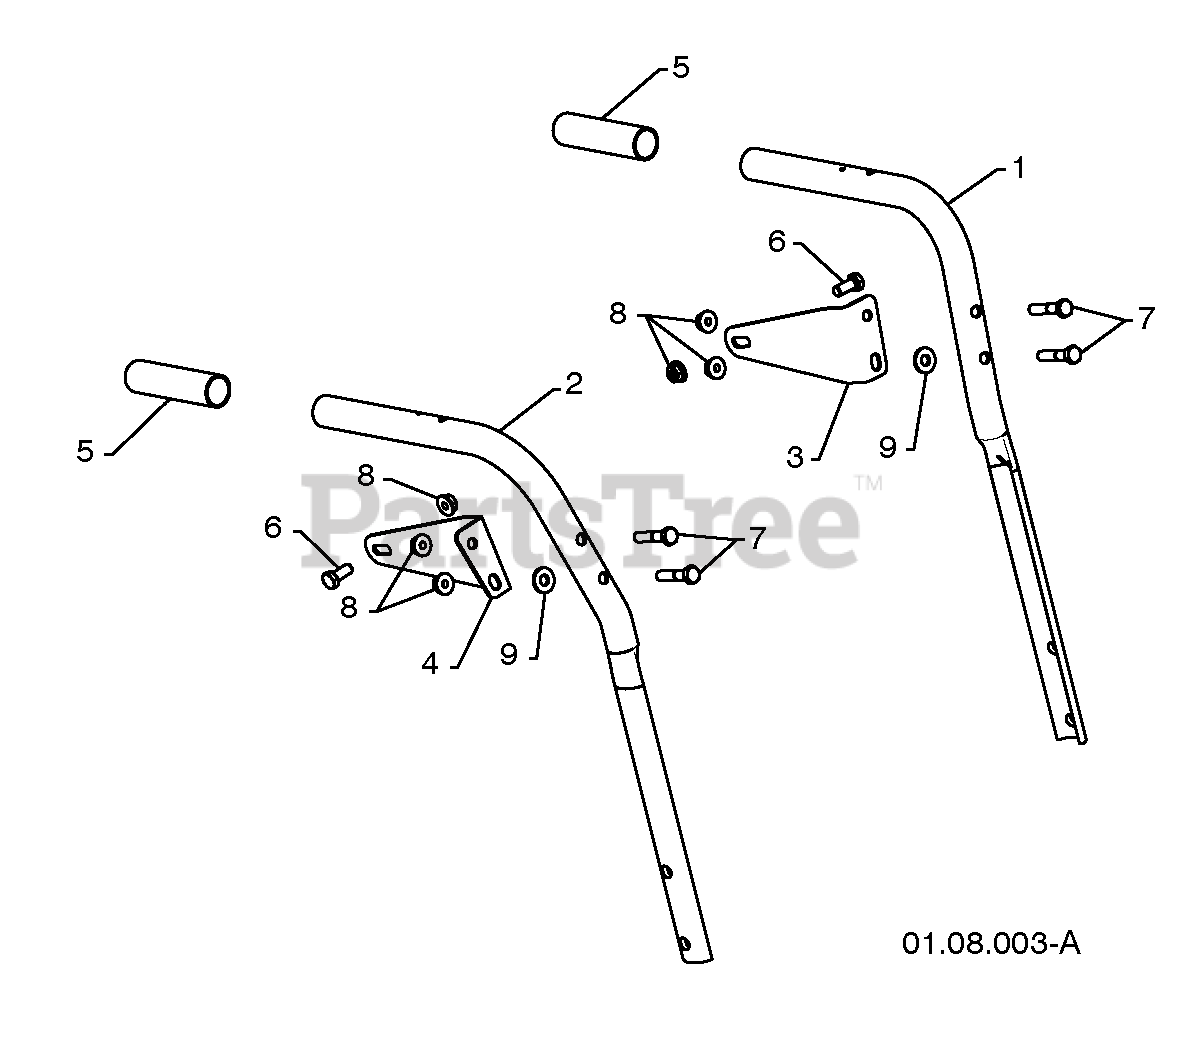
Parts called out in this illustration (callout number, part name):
1	PLOW HANDLE LH
2	PLOW HANDLE RH
3	PANEL BRACKET LH
4	PANEL BRACKET RH
5	HANDLE GRIP
6	SCREW 5/16-18 X .750
7	SCREW 5/16-18 X 1.50
8	NUT 5/16-18
9	WASHER
